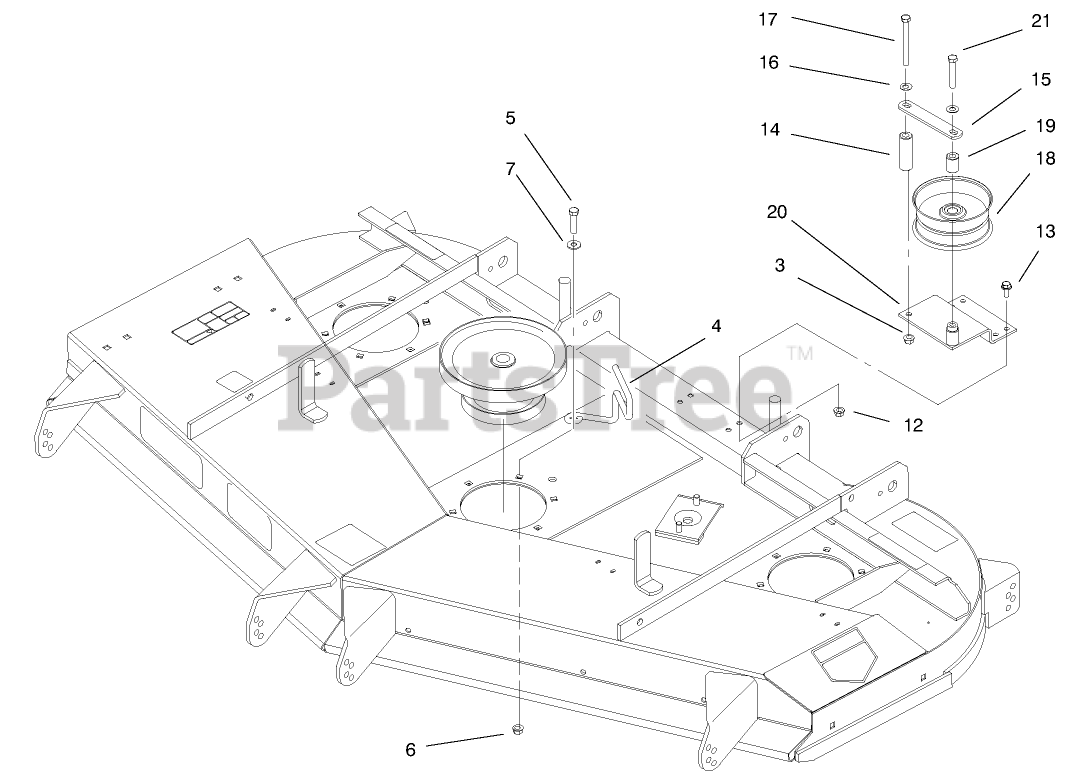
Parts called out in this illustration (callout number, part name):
3	NUT-HHF, WHIZ
4	GUIDE-BELT
5	SCREW-HH
6	NUT-HF
7	WASHER-FLAT
12	NUT-HF
13	SCREW-HHF
14	SPACER-BRACKET
15	Plate-Guide Belt
16	Washer
17	SCREW-HH
18	Pulley
19	Spacer
20	BRACKET-PULLEY
21	SCREW-HH
